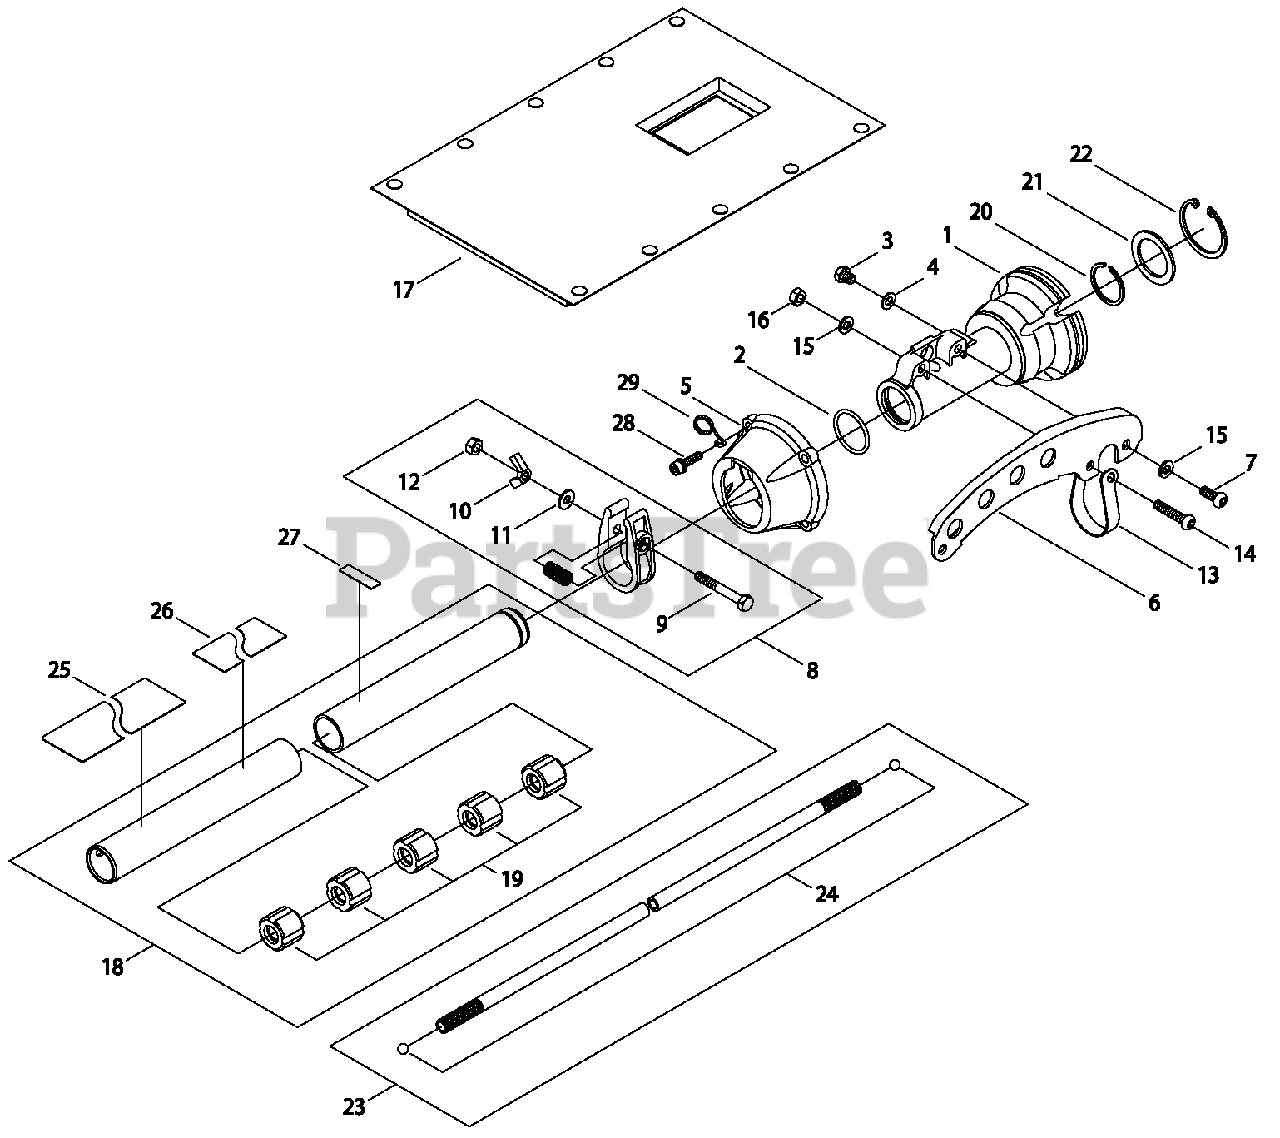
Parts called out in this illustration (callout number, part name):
1	SWIVEL JOINT
2	O-RING
3	BOLT - 6X8
4	WASHER - 8
5	CONNECTOR, CAP
6	HANGER
7	SCREW - 6X16
8	SWIVEL LOCK ASSY
9	BOLT
10	WINGNUT - 6
11	WASHER - 6
12	LOCKNUT - 6
13	CLAMP
14	SCREW - 6X30
15	LOCKWASHER - 6
16	LOCKNUT - 6
17	PROTECTOR
18	MAIN PIPE ASSY
19	BUSHING
20	RING, RETAINING
21	STOPPER
22	RING, RETAINING - 40
23	DRIVESHAFT ASSY
24	STOPPER
25	LABEL - SHINDAIWA PROFESSIONAL
26	LABEL - CAUTION
27	LABEL - HANDLE LOCATION
28	SCREW - 5X20
29	HOLDER, CABLE
